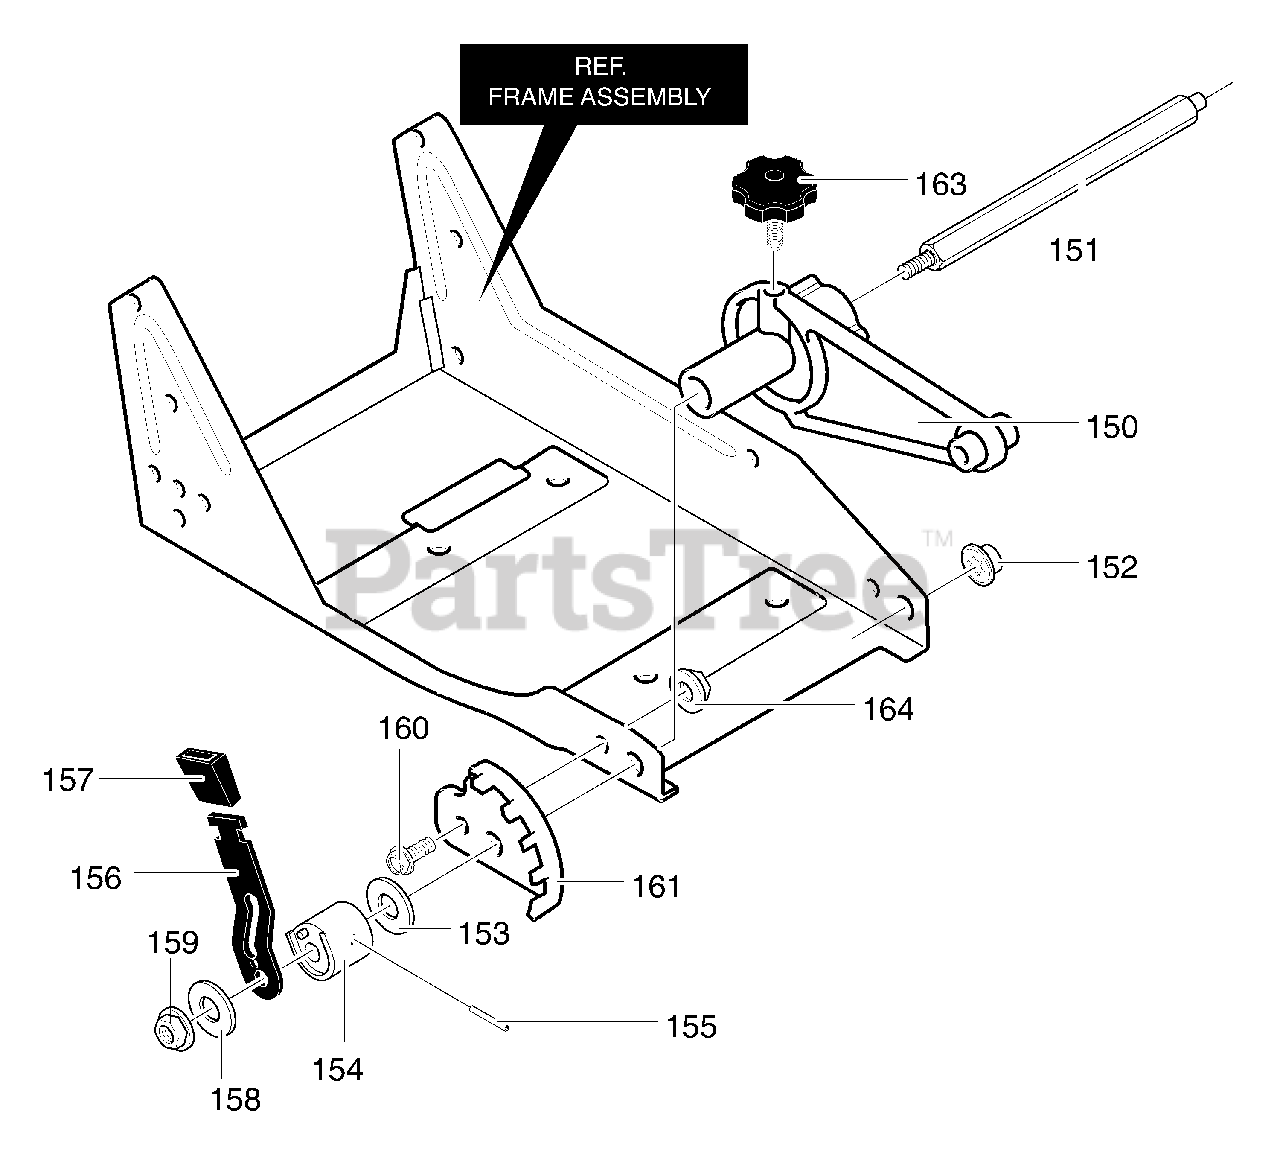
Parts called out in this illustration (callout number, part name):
150	Front Wheel Arm
151	Rod, Front Mount Curb
152	Pushnut, Washer
153	Plastic Washer
154	Spacer, Height Adjust
155	Pin, Spring
156	Lever, Height Adjust
157	Knob,Rectangle
158	Flatwasher
160	Screw, 5/16 18x.63
161	Plate, Height Adjust
163	Knob,Molded
164	Nut, 5/16 18
